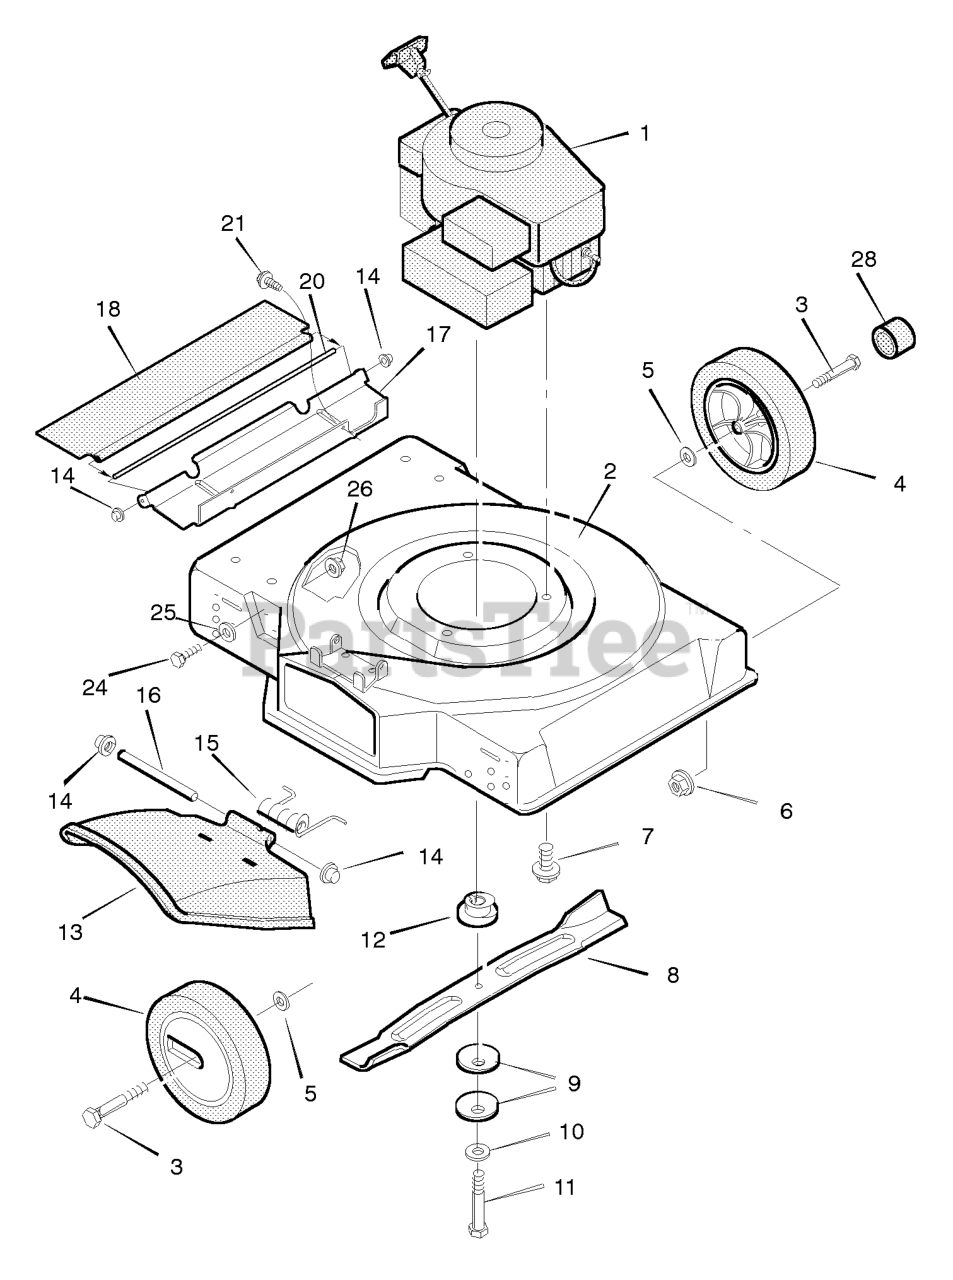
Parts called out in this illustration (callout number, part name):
1	Engine *
2	Housing
3	Bolt, Axle
4	Wheel and Tire *
6	Locknut, Flange
7	Bolt, Engine
9	Washer, Belleville
11	Bolt, Hex
12	Adapter, Blade
13	Deflector, Chute
14	Push- On Cap
16	Pin, Pivot
17	Extension, Rear
18	Deflector, Rear
24	Bolt, Hex
26	Locknut, Flange
28	Hub Cap
